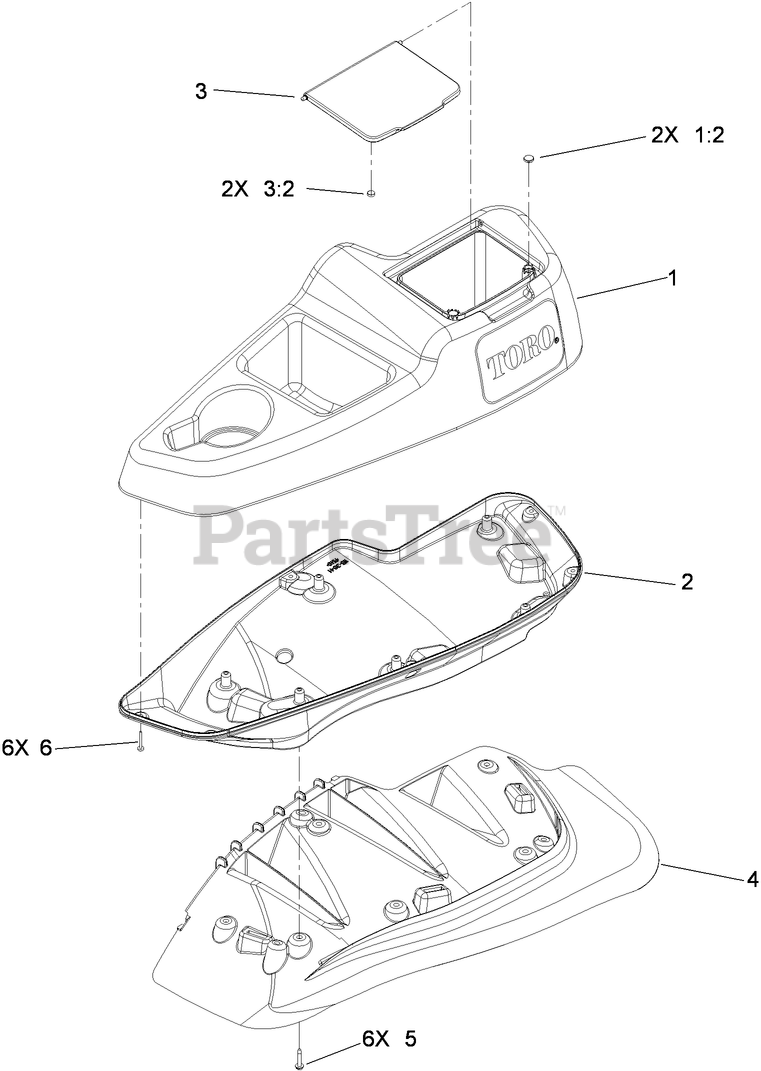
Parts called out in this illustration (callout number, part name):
1	LH WIDE CONSOLE TOP ASM
2	CONSOLE-LOWER, LH WIDE
3	WIDE LID ASM
3:2	MAGNET
4	FENDER-WIDE, LH
5	SCREW-THREAD FORMING
6	SCREW-PPH
